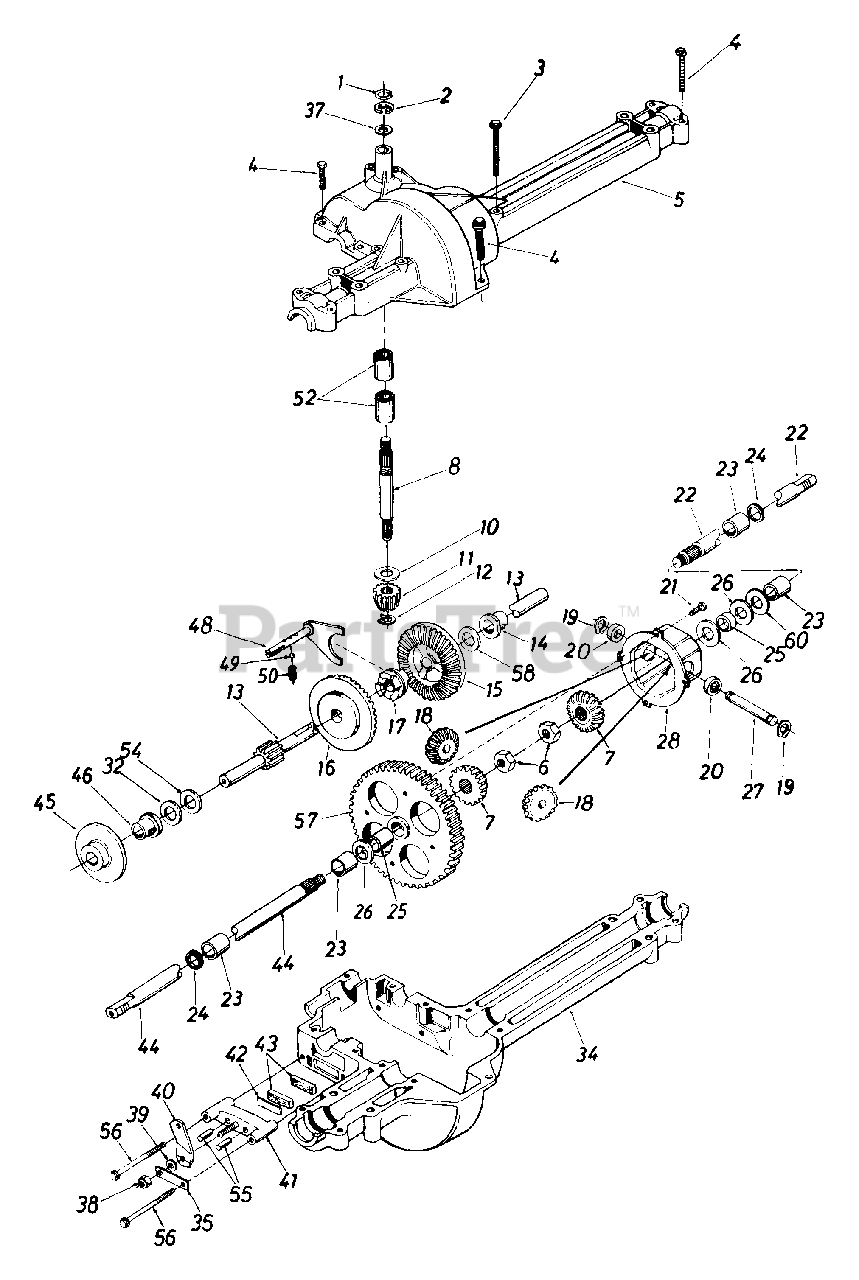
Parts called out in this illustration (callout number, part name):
3	Hex Bolt 1/4-20 x 1.75" Lg.
4	Hex Tap Scr. 1/4-20 x 1.25" Lg.
5	Upper Housing
6	Hex Jam Nut 1/2-20 Thd.
7	Miter Gear
10	Thrust Washer 5/8" I.D. x 1.25" O.D.
11	Pinion Input 14T
12	Retaining Ring
13	Drive Shaft - L.H. Brake
14	Flange Brg. 5/8" I.D. x 3/4" Lg.
15	Bevel Gear 42T - Small I.D.
16	Bevel Gear 42T - Large I.D.
17	Clutch Collar
18	Miter Gear 15T (H.D.)
19	Snap Ring
20	Thrust Bearing
21	Pan Head Scr. 1/4-20 x .50" Lg. w/Patch
22	Axle R.H.
23	Sleeve Bearing 3/4" I.D. x 1.0" Lg.
24	Oil Seal 3/4" I.D.
26	Fl-Wash. .760" I.D. x 1.5" O.D.
28	Differential Can Ass'y.
32	Washer
34	Lower Housing
35	Anti-Rotation Brkt.
37	Washer
38	Hex Nut 5/16-24 Thd.
39	Fl-Wash. .344" I.D. x .875" O.D.
40	Actuating Arm
41	Brake Yoke
42	Puck Plate
43	Brake Puck
44	Axle L.H.
46	Flange Bearing 5/8" I.D. x 15/16" Lg.
48	Shift Fork Ass'y.
49	Ball Detent .250" Dia.
50	Spring Detent
52	Needle Brg. 5/8" I.D. x 1/2" Lg.
54	Fl-Wash. 5/8" I.D. x 1" O.D. x .020 Thk
55	Actuating Pin 5/16" Dia
56	Hex Wash Hd. Self-Tap Scr. 1/4-20 Thd.
57	Differential Gear 58T
58	Fl-Wash. 5/8" I.D. x 1" O.D. x .020 Thk.
60	Washer
